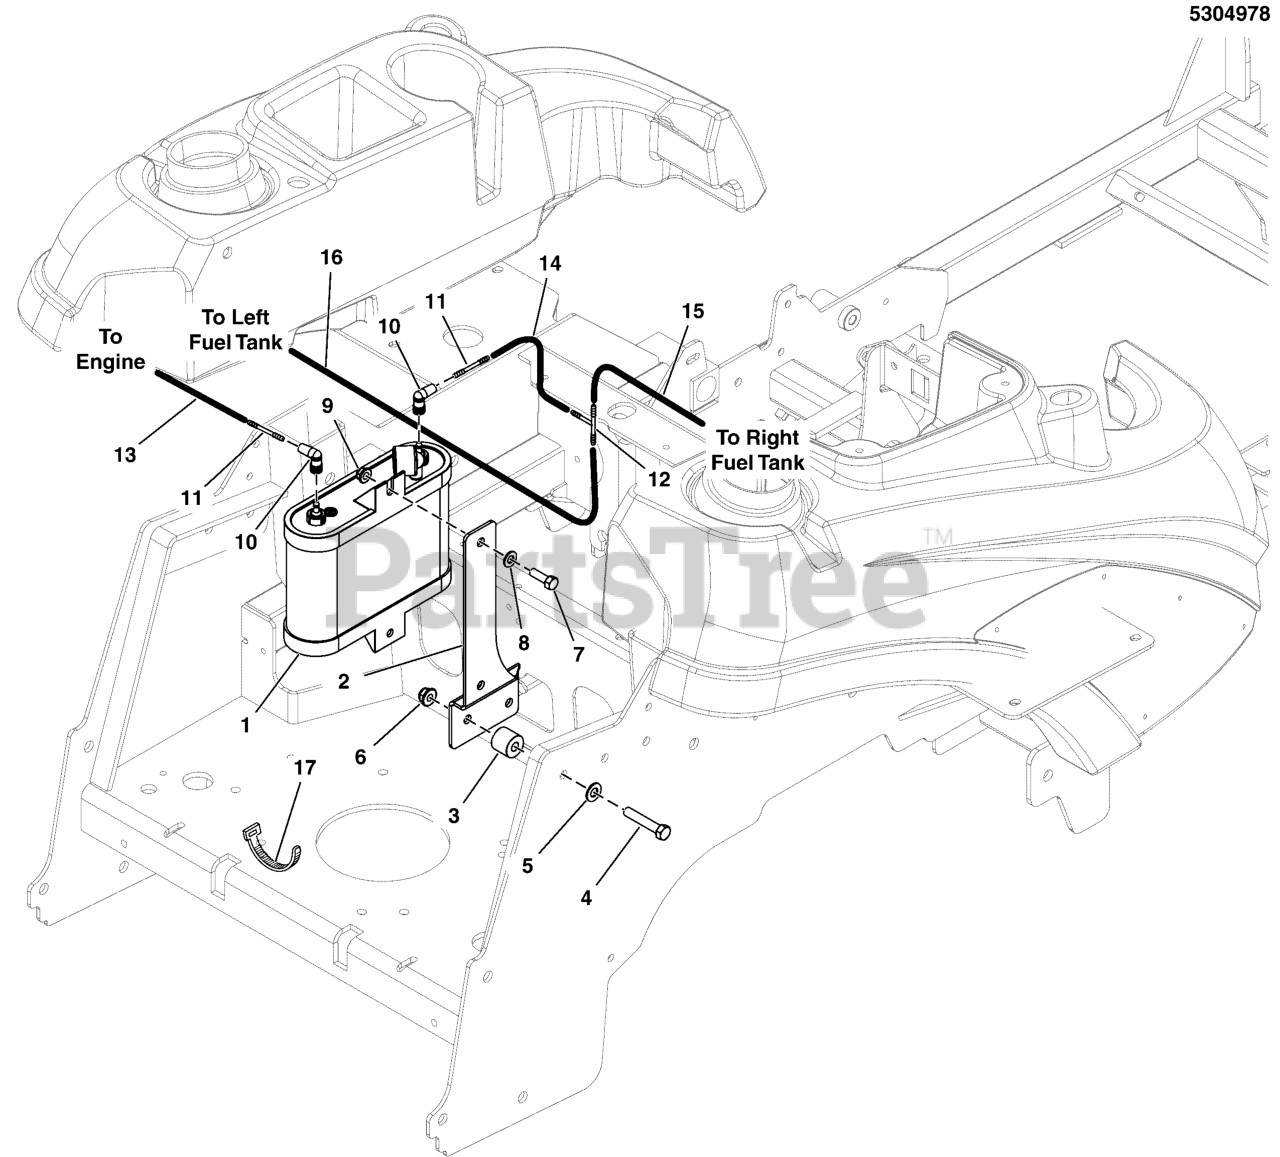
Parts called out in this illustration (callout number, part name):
1	CARBAN CANISTER, 1 LITER, 12.8 GAL CAP
2	PLATE, EVAP CAN MNT, IS2100 - BLK
3	SPACER, .39 X 1.00 X .88, CZ
4	BOLT, 3/8-16 X 2, GD5, CZ
5	WASHER, 3/8 SAE
6	NUT, 3/8-16 HEX NYLOCK FLANGE
7	BOLT, 5/16-18 X 1 GD5 CZ
8	WASHER, 5/16" SAE
9	NUT, 5/16-18 HEX NYLOCK FLANGE
10	FITTING, 90 DEG, 3/16X3/16, SANTOPRENE
11	FITTING, STRAIGHT, 3/16X3/16, PLASTIC
12	FITTING, 3/16" TEE, BARB TYPE, HDPE
13	HOSE, VAPOR, 5MM ID, 23.00 LG
14	HOSE, VAPOR, 5MM ID, 20.00 LG
15	HOSE, VAPOR, 5MM ID, 15.00 LG
16	HOSE, VAPOR, 5MM ID, 30.00 LG
17	TIE, SELF-LOCKING, 12"
